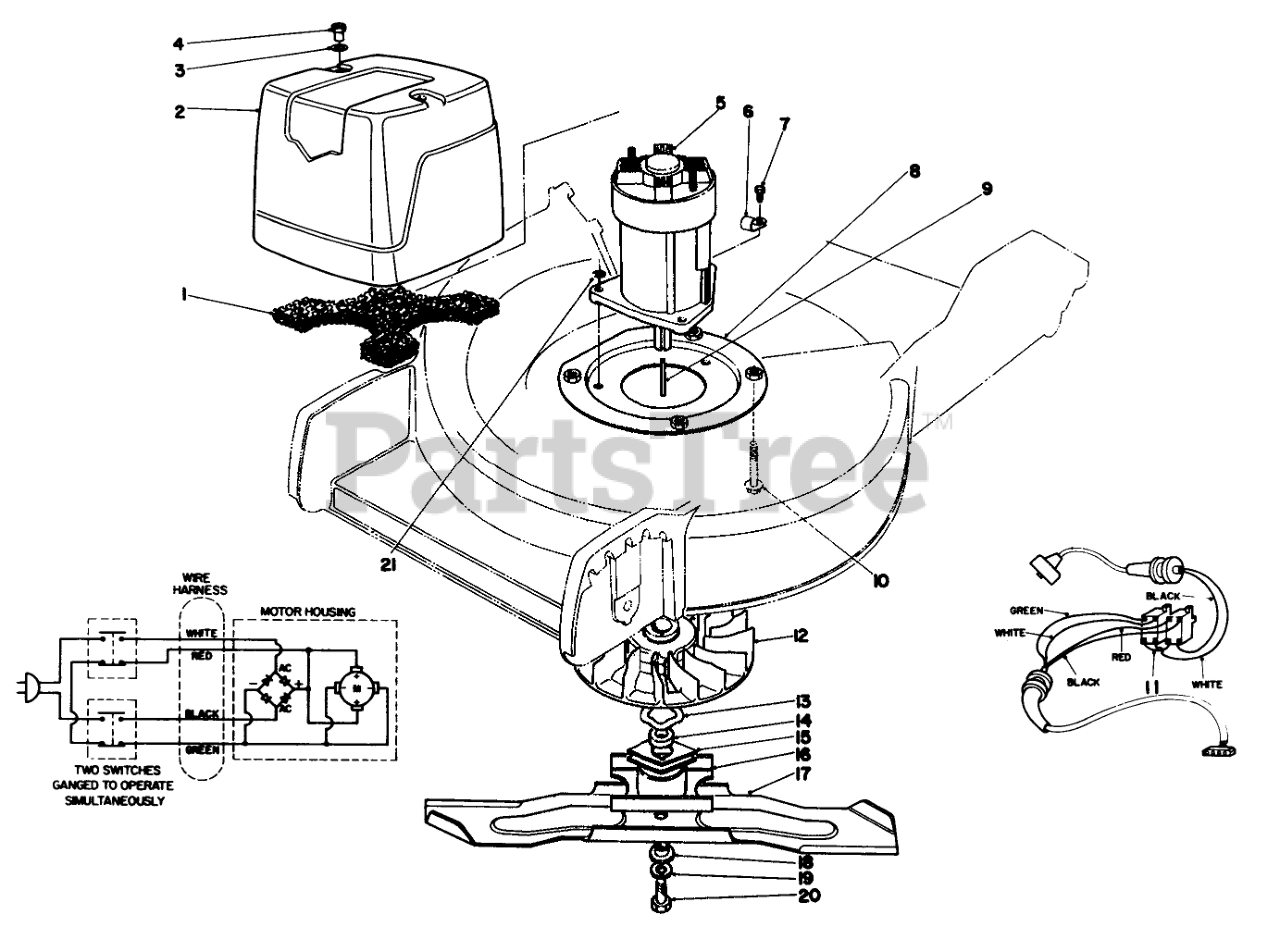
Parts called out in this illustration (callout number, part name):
1	FILTER F/W
2	MOTOR SHROUD F/W
3	WASHER F/W
4	NUT F/W
5	Motor-Electric
6	CLIP-CLOSED, INSULATED
7	SCREW-HH
8	MOTOR MOUNT ASM WA
9	1/8 X 1/40 SQUARE KEY
10	SCREW-HHF
11	BRAKE WIRE
12	FAN F/W
13	WAVE WASHER
14	BLADE RETAINER SPACER
15	FAN DRIVER
16	BLADE RETAINER WA
17	Blade
18	BLADE SPACER
19	WASHER-LOCK/SP
20	SCREW-HH
21	WASHER-LOCK/EXT
